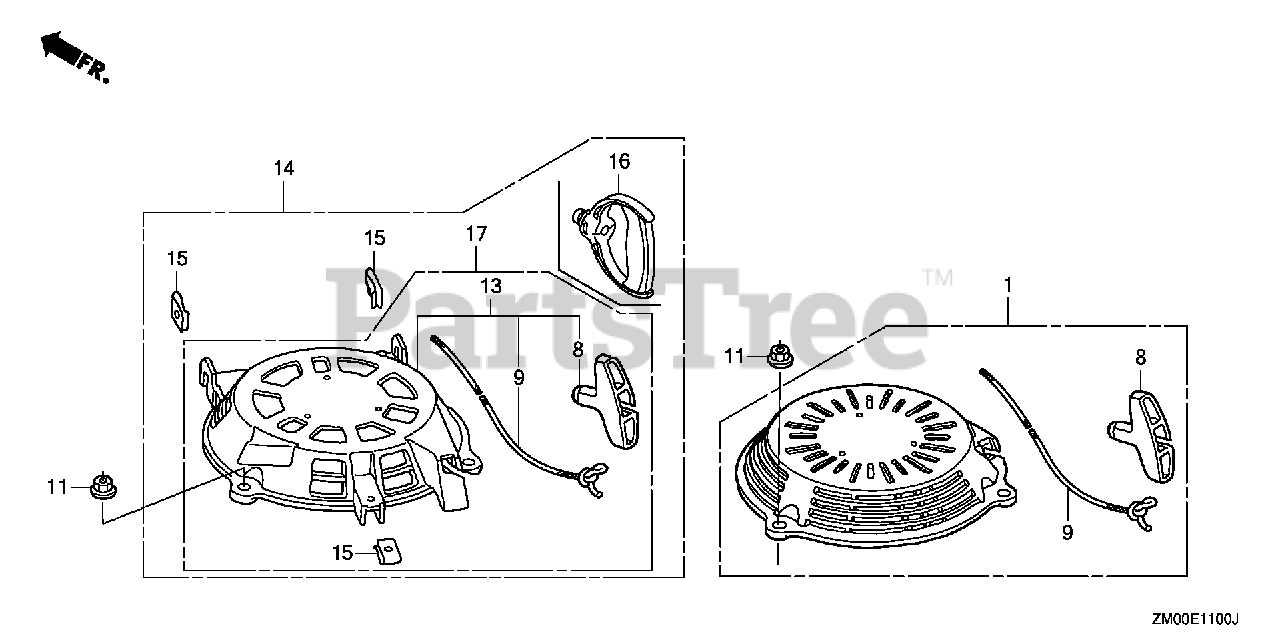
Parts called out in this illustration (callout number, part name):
1	STARTER ASSY. *NH1*
8	KNOB, RECOIL STARTER
9	ROPE, RECOIL STARTER (LONG TYPE)
11	NUT, FLANGE (6MM)
